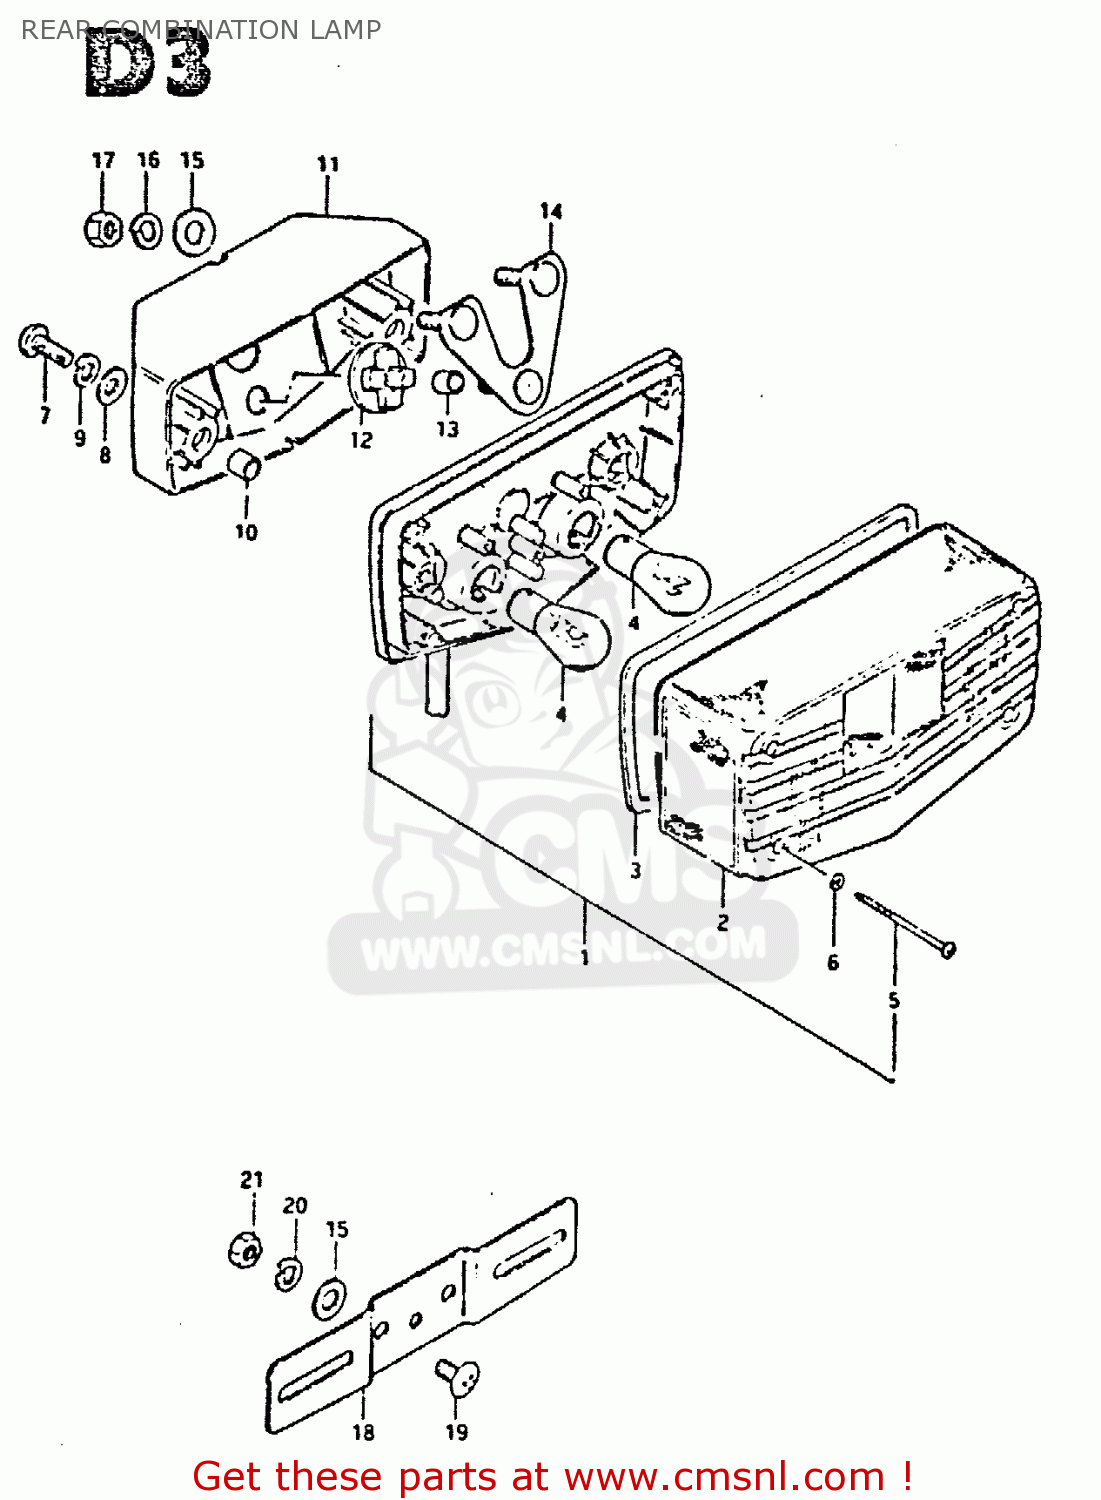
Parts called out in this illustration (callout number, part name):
1	LAMP UNIT, REAR COMBINATION
2	LENS
3	GASKET,REAR COMBINATION LAMP LENS (NAS)
4	BULB(12V21/5W)
5	SCREW
6	GASKET (NAS)
7	SCREW
8	WASHER
9	LOCK WASHER
10	SPACER,REAR COMBINATION LAMP
11	BRACKET UNIT,TAIL LAMP
12	CUSHION,REAR COMBINATION LAMP
13	SPACER,REAR COMBINATION LAMP
14	PLATE,REAR COMBINATION LAMP
15	WASHER
16	LOCK WASHER
17	NUT
18	PLATE, LICENCE
19	SCREW
20	LOCK WASHER
21	NUT
